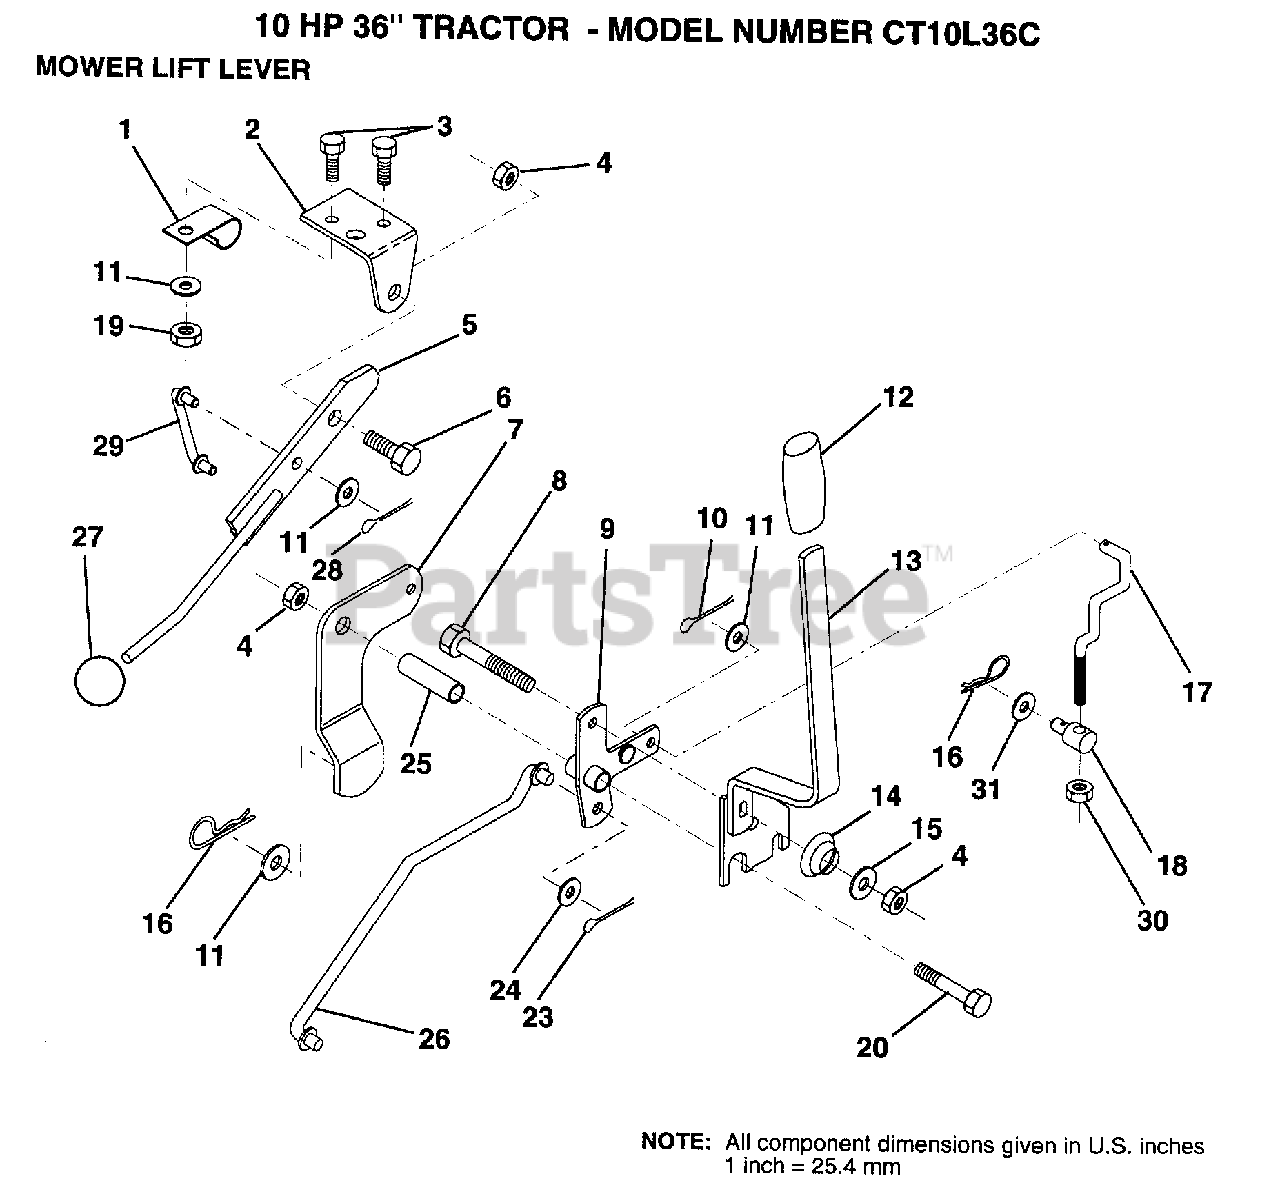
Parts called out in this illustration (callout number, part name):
1	"CLIP,INSULATOR"
2	BRKT CLUTCH
3	BOLT
4	NUT
5	CLUTCH LEVER AS
6	"BOLT, SHOULDER LT"
7	MWR CLUTCH ARM AS
8	BOLT
9	"BELLCRANK,LIFT"
10	COTTER PIN
11	WASHER
13	HANDLE.ASM.LIFT
14	SPRING COMPRESSIO
15	WASHER T
16	SPRING.RETAINER
17	"LINK,LIFT FRT"
18	TRUNION
20	BOLT
23	PIN COTTER 1/8
25	TUBE SPACER
26	ROD LIFT MOWER
27	KNOB T(3/8 HOLE)
29	CLUTCH LINK
30	NUT
31	WASHER
